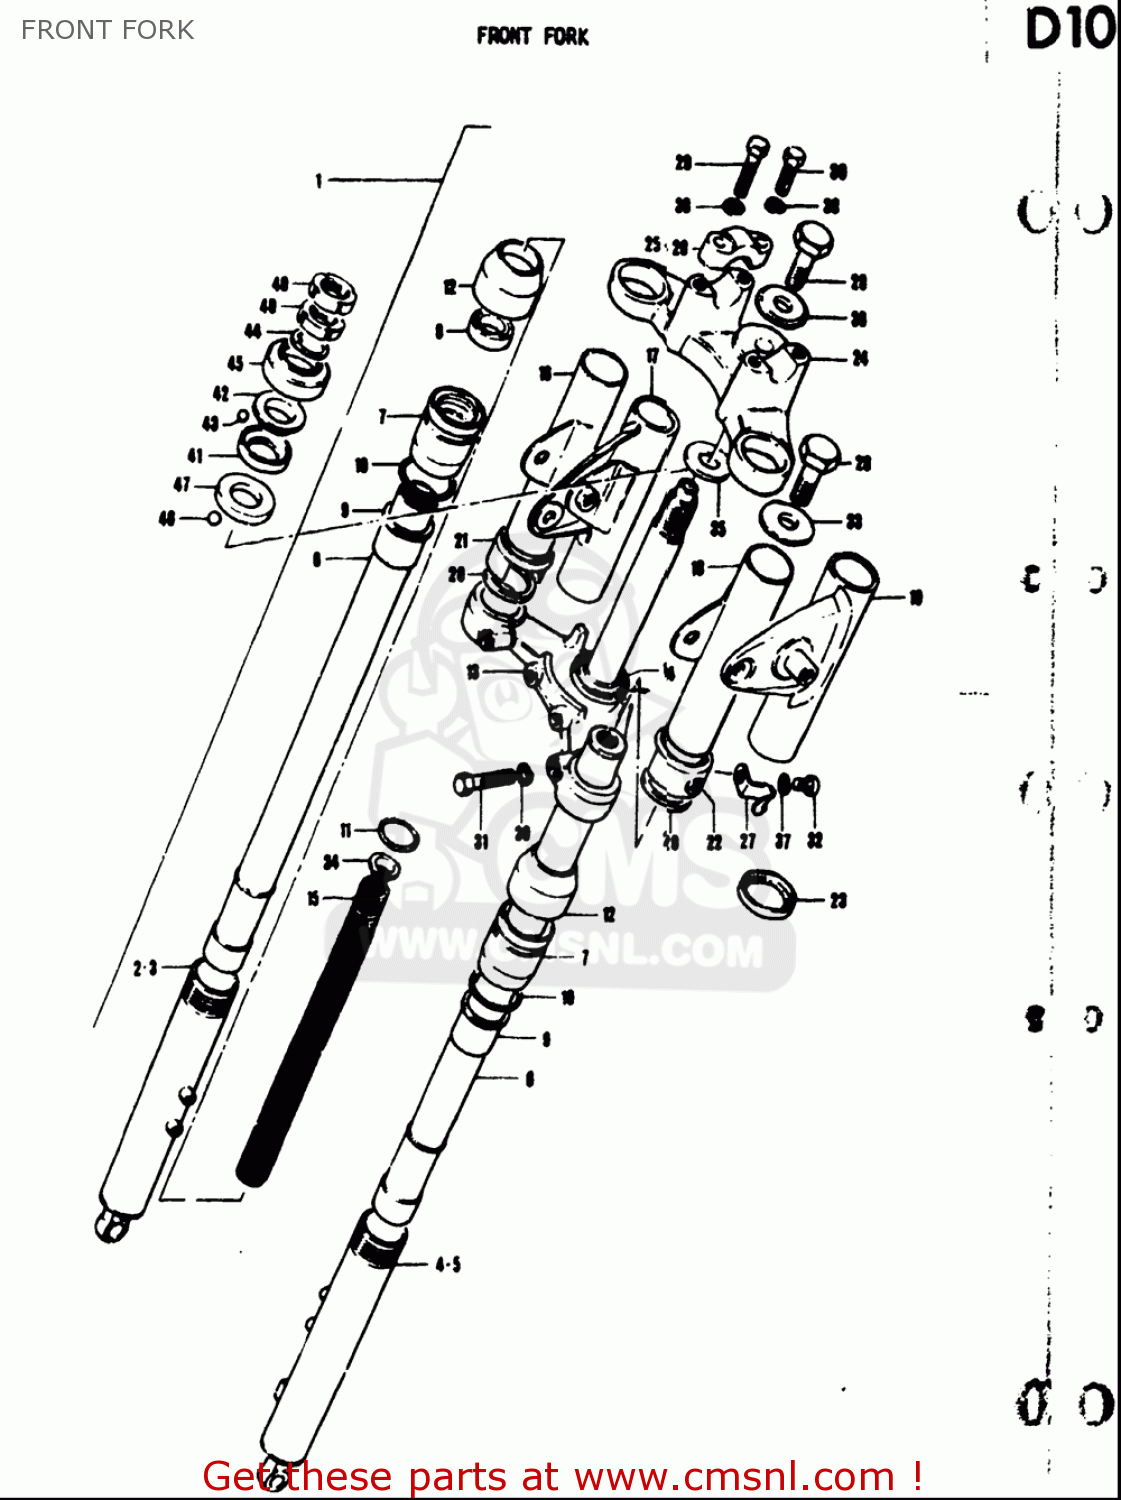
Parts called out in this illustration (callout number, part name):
9	GUIDE,FORK INNER TUBE
11	O RING
23	SEAT,HEADLAMP BRACKET
25	HOLDER,HANDLEBAR
28	BOLT,FR FORK(10X33)
30	BOLT
32	SCREW
33	WASHER
36	WASHER
37	WASHER,LOCK
38	WASHER,LOCK
39	WASHER,LOCK
41	RACE,STEERING INNER UPR
42	LACE,STEERING OUTER UPR
43	BALL
46	BALL
47	LACE,STEERING INNER LWR
